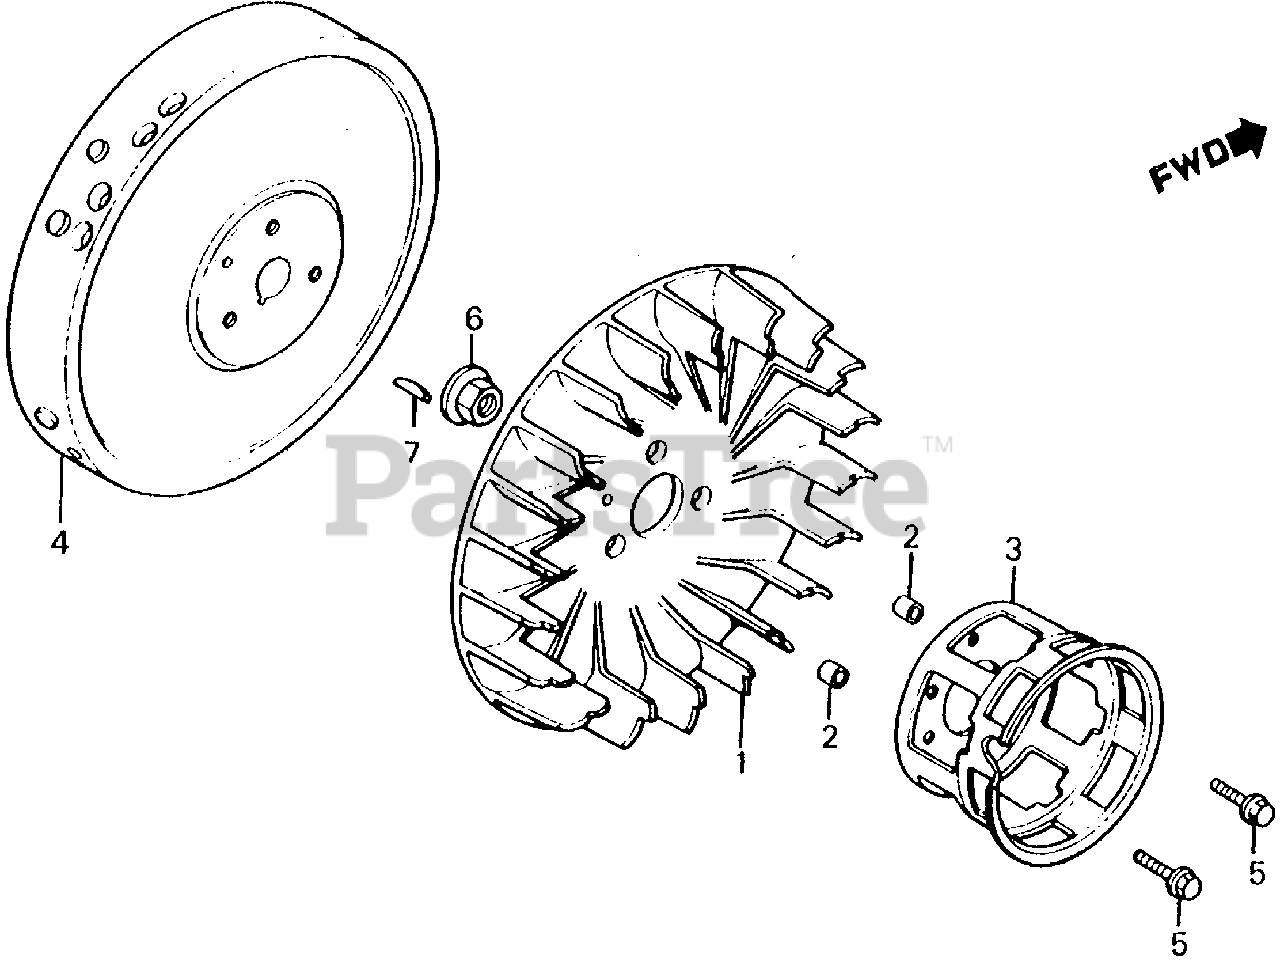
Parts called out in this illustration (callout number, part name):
1	FAN, COOLING
2	COLLAR, FAN
3	PULLEY, STARTER
4	FLYWHEEL (C.D.I.)
5	BOLT, FLANGE (6X16)
6	NUT, SPECIAL (14MM)
7	KEY, SPECIAL WOODRUFF (25X18)
